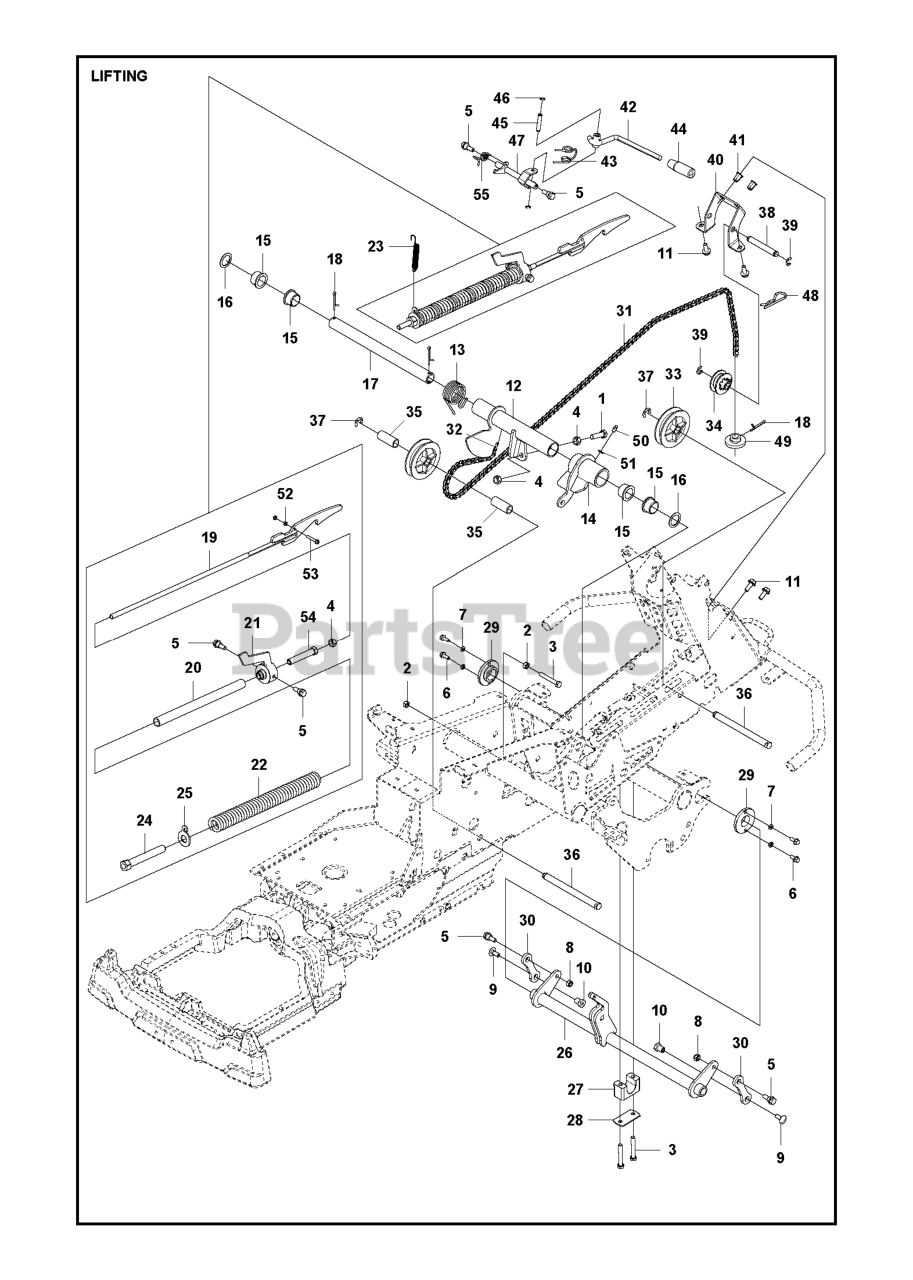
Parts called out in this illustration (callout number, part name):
2	NUT
6	SCREW
8	LOCKNUT M8
15	BEARING FLANGE
39	RETAINING RING
46	FASTENER
50	GREASE NIPPLE
51	WASHER - M6
52	LOCKNUT M5
